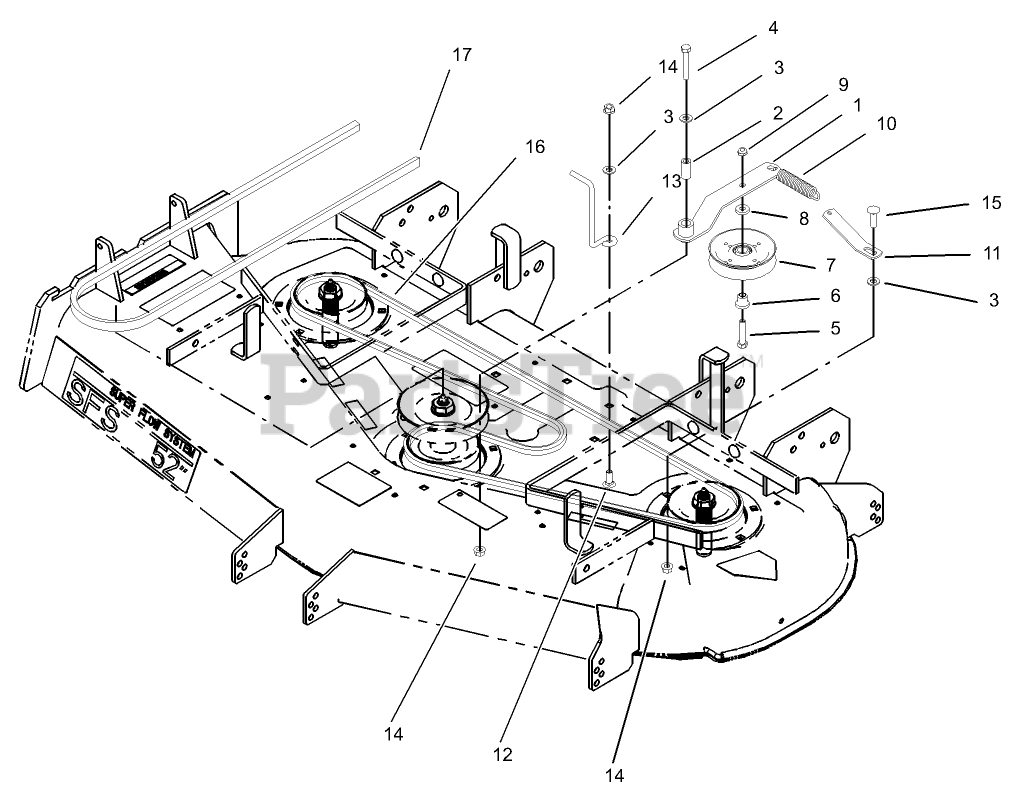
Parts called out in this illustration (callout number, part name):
1	IDLER ARM ASM
2	SLEEVE
3	WASHER-FLAT
4	SCREW-HH
5	SCREW-HH
6	BUSHING-PULLEY
7	PULLEY-IDLER
8	WASHER-FLAT
9	NUT-HEX
10	SPRING-EXTENSION
11	PLATE-SPRING
12	SCREW-CARR
13	GUIDE-BELT
14	NUT-HF
15	SCREW-CARR
16	V-BELT
17	BELT (52)
